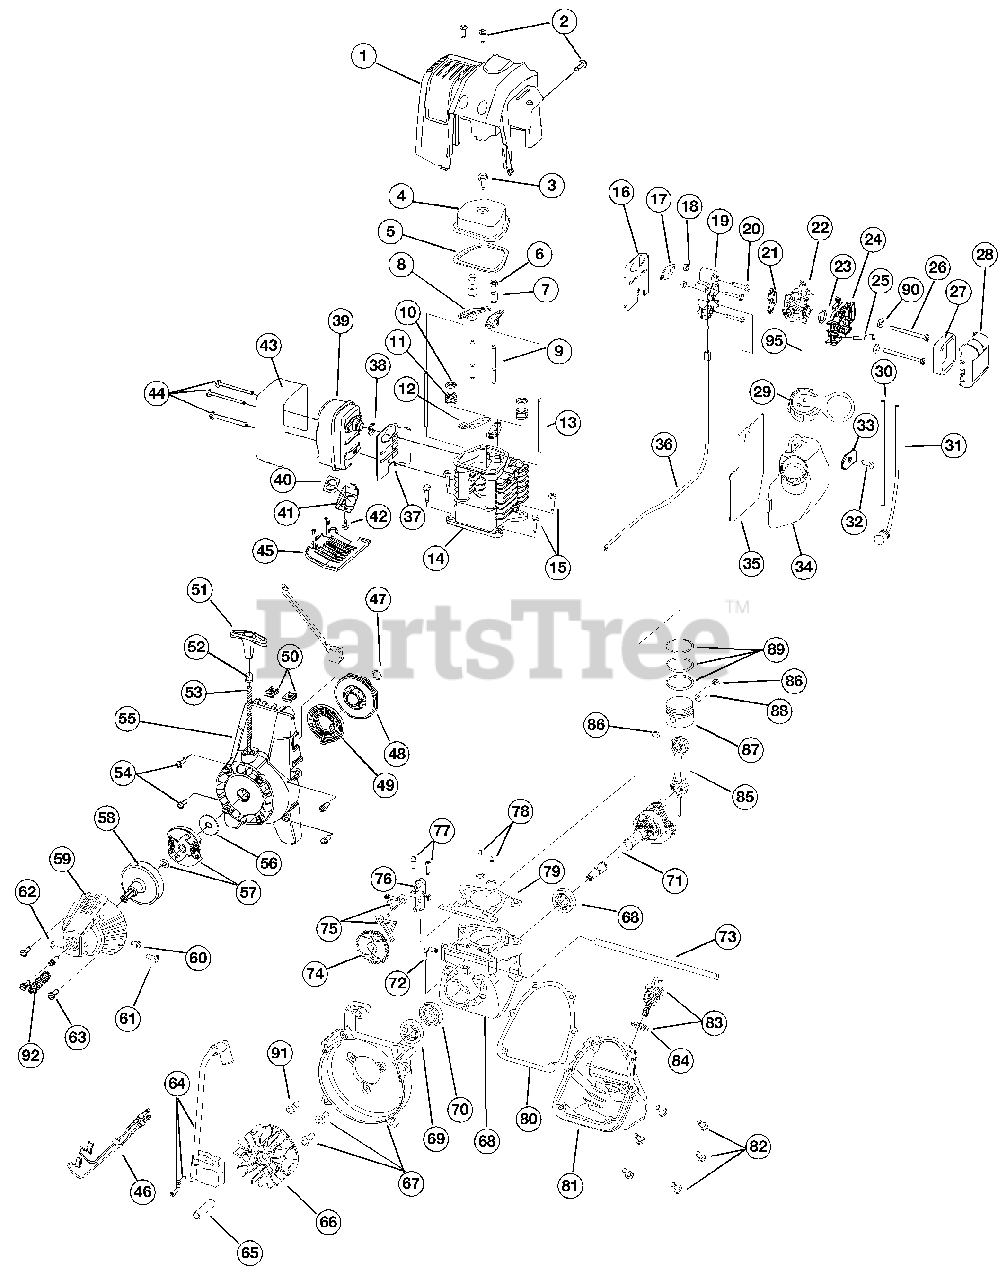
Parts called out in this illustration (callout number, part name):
1	Engine Cover
2	Engine Cover Screws
3	Valve Cover Screw
4	Valve Cover
5	Valve Cover Gasket
6	Rocker Adjustment Nut
7	Rocker Arm Pivot
8	Rocker Arm
9	Rocker Arm Stud
10	Valve Spring Retainer
11	Valve Spring
12	Push Rod Guide
13	Push Rod
14	Cylinder Head
15	Cylinder Screw
16	Intake Baffle
17	Carburetor Mount Gasket
18	Nut
19	Carburetor Mount
20	Carburetor Mount Screw
21	Carburetor Gasket
22A	Carburetor with Primer
22B	Carburetor with Primer
23	O-Ring, Carburetor
24	Air Filter/Choke Cover Assembly
25	Breather Tube
26	Air Filter Mounting Screw
27	Air Filter
28	Air Filter Cover
29	Fuel Cap
30	Fuel Return Line
31	Fuel Pick-Up Line with Filter
34	Fuel Tank Assembly
35	Fuel Tank Shield
36A	Throttle Cable
36B	Throttle Cable
37	Muffler Baffle
38	Muffler Gasket
39	Muffler
40	Spark Arrestor Screen
41	Screen Cover
43	Muffler Shield
44	Muffler Mounting Screw
45	Muffler Cover
46	Switch Wire Assembly
47	Palnut
48	Recoil Pulley
49	Recoil Spring
50	Nut Clip
51	Pull Handle
52	Rope Guide
54	Starter Housing Screw
55	Starter Housing Assembly
56	Clutch Washer
57	Clutch with Spacer
58	Clutch Drum
59	Clutch Cover
60	Anti-Rotation Screw
61	Screw
63	Clutch Cover Screw
64	Ignition Module with Screws
66	Flywheel
67	Shroud Assembly with Screws
68	Crankcase Assembly
69	Oil Seal
70	Bearing
71	Crankshaft
72	90° Elbow
73	Breather Hose
74	Cam Gear
75	Cam Follower Set
76	Cam Bracket
77	Cam Bracket Screw
78	Valves, Intake and Exhaust
79	Cylinder Gasket
80	Oil Pan Gasket
81	Oil Pan
82	Oil Pan Screw
83	Dipstick Assembly
85	Connecting Rod
86	Wrist Pin Button
87	Piston
88	Wrist Pin
89	Piston Ring Set
92	Compression Spring
